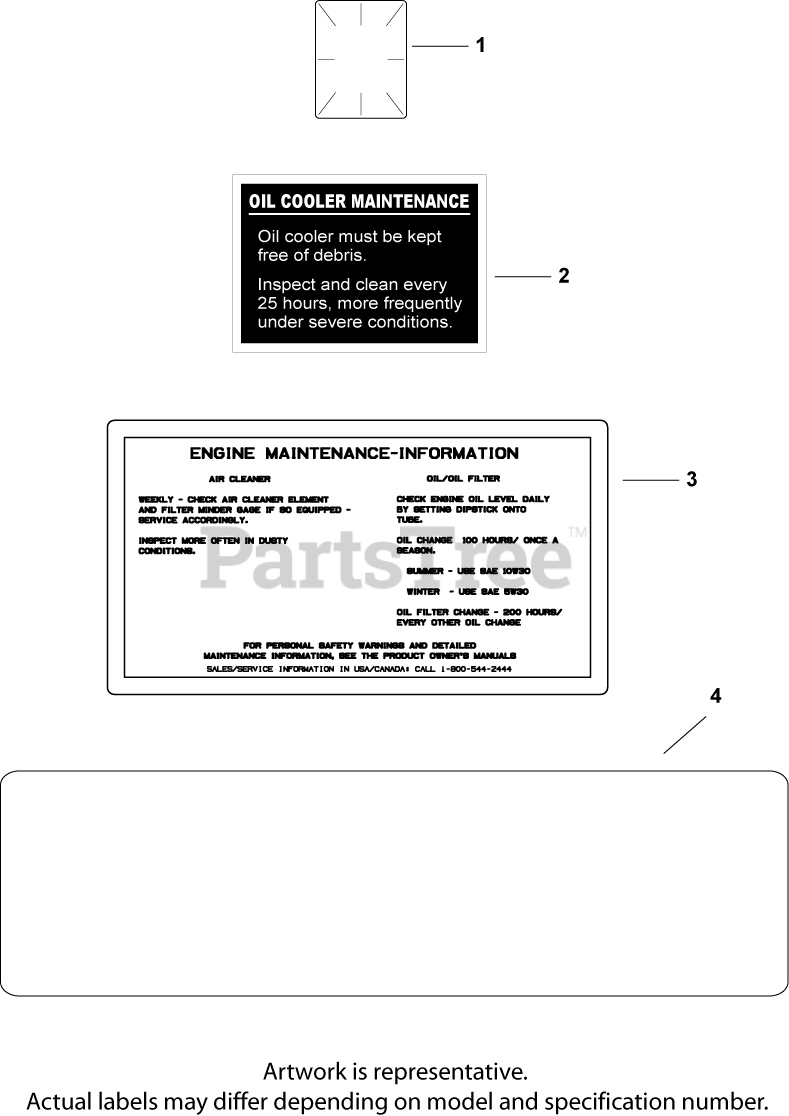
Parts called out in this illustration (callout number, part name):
1	DECAL, CLEAR LAMINATE USE 25 113 70-S
2	DECAL, OIL COOLER - (#DSC)
3	DECAL, AIR CLEANER - (#DSC)
4	DECAL, 27 HP
